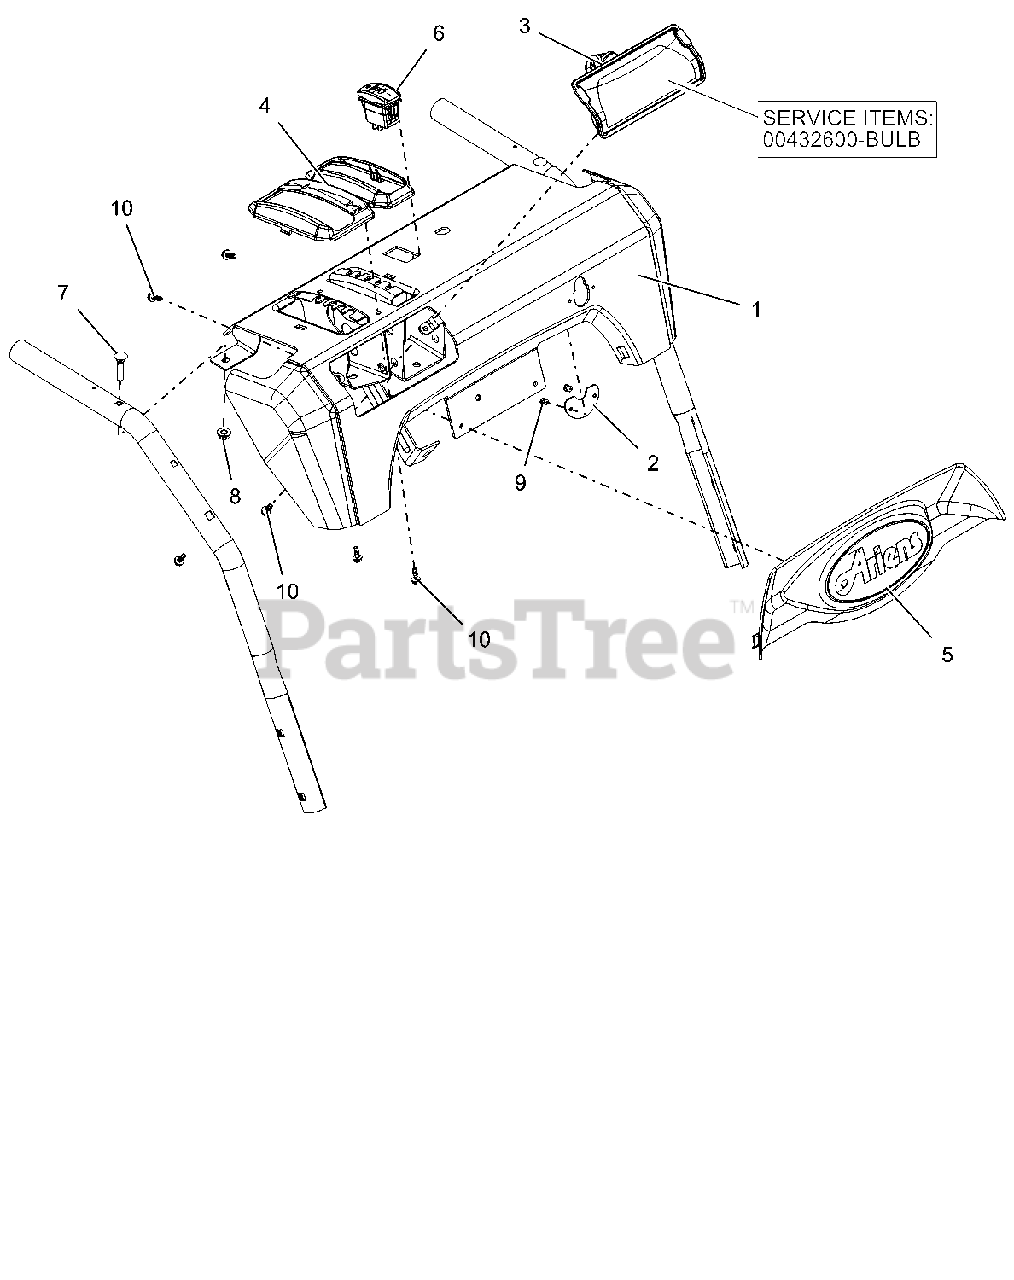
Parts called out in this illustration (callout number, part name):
1	CONTROL PANEL W/DECAL FRIC-ID
2	COVER, DASH BRKT, ID
3	BULB, LIGHT-HALOGEN 20W
3	HEADLIGHT ASY, HALO 20W 2SHOT
4	BEZEL, SHIFT - FRICTION SNOW
5	BEZEL, DASH-ARIENS LG DASH
6	SWITCH,ROCKER SPST-ON/OFF
7	BLT-RDHDXLSQNK.25-20X1.25 G5ZC
8	@NUT-LK-CTR-FLG .25-20 YWZC
9	RVT-POP #43 .125X.313 STL ZINC
10	SCR-TAP #10X.50 BOSS INDHXHD
